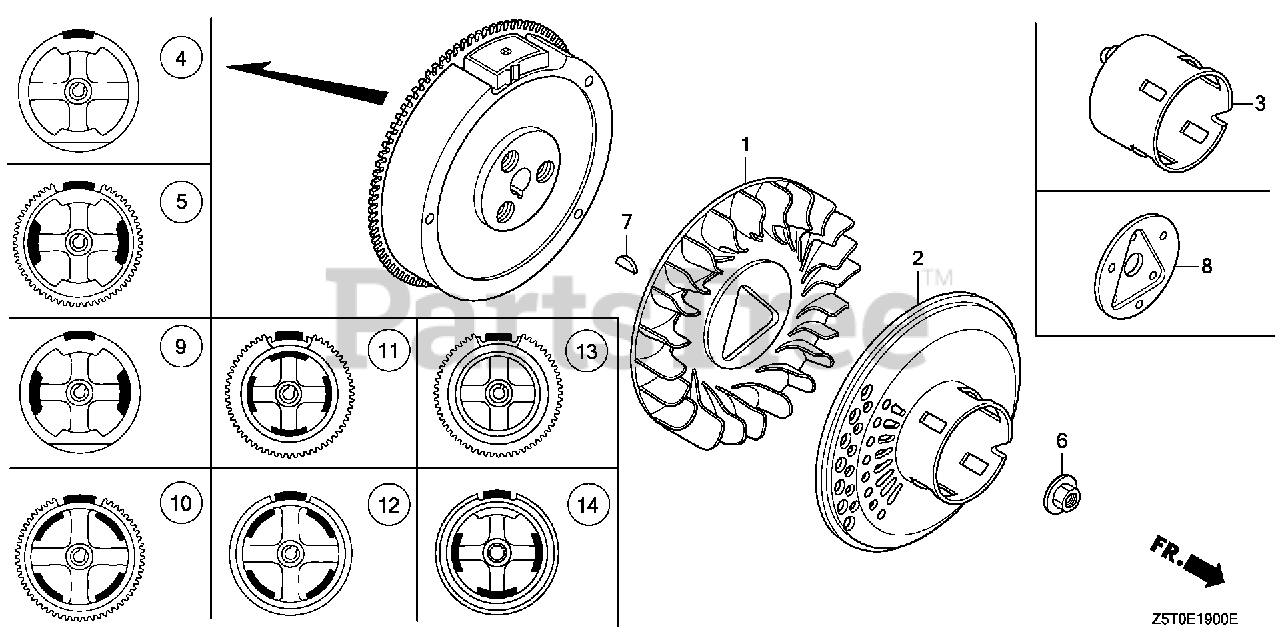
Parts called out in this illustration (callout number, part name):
1	FAN, COOLING
2	PULLEY, STARTER (SCREEN GRID)
6	NUT, SPECIAL (16MM)
7	KEY, SPECIAL WOODRUFF (25X18)
11	FLYWHEEL (SEL)
